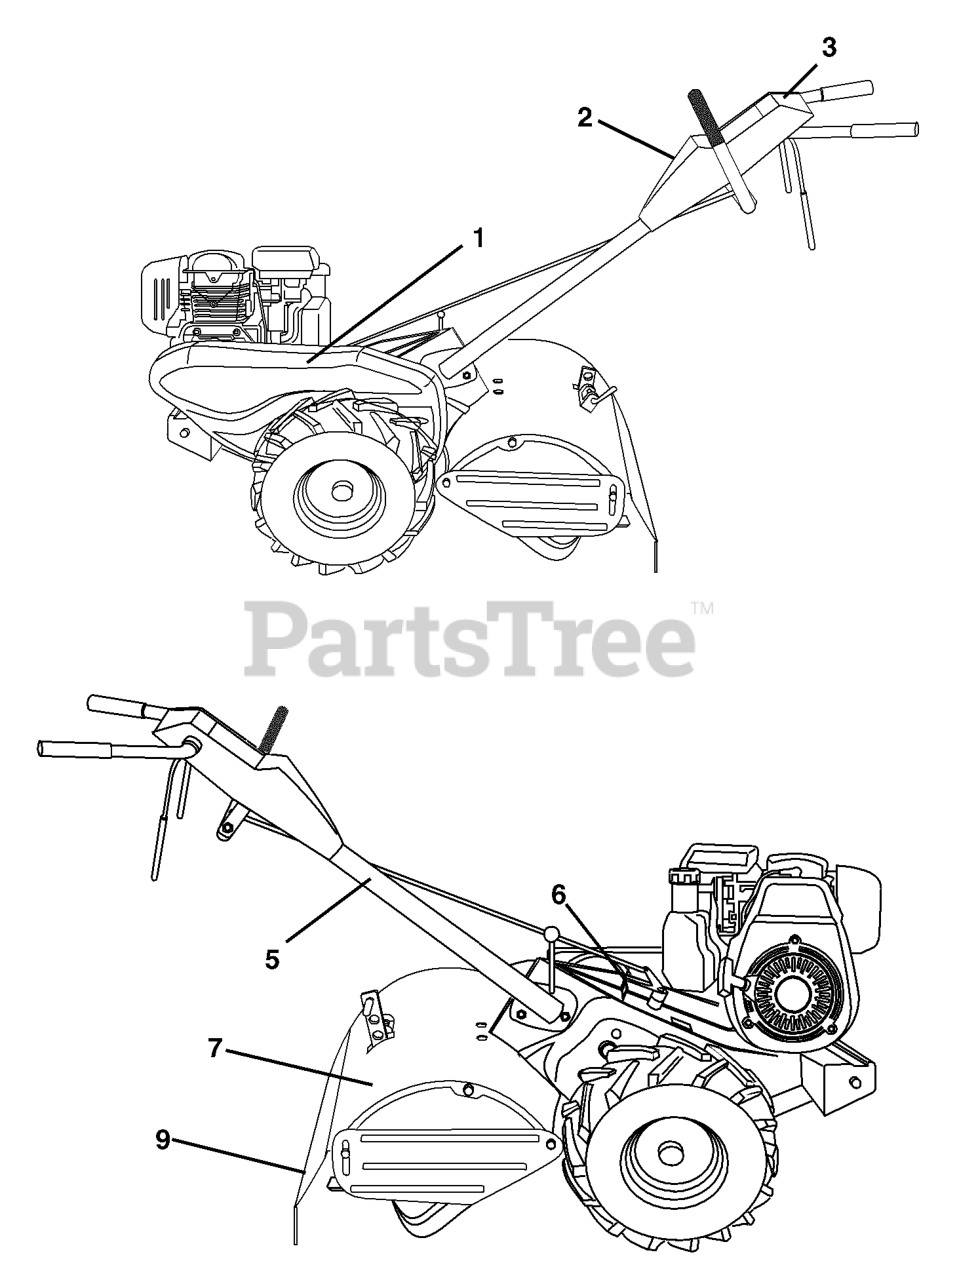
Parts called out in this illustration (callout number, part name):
1	DECAL, BLT GRD
2	DECAL, CNTRL PNL
3	DECAL, LOGO
5	DECAL TI (2 2)
6	DECAL.SHIFT.INDICATOR.TILLER
7	DECAL -CAUTION
9	DECAL TI
